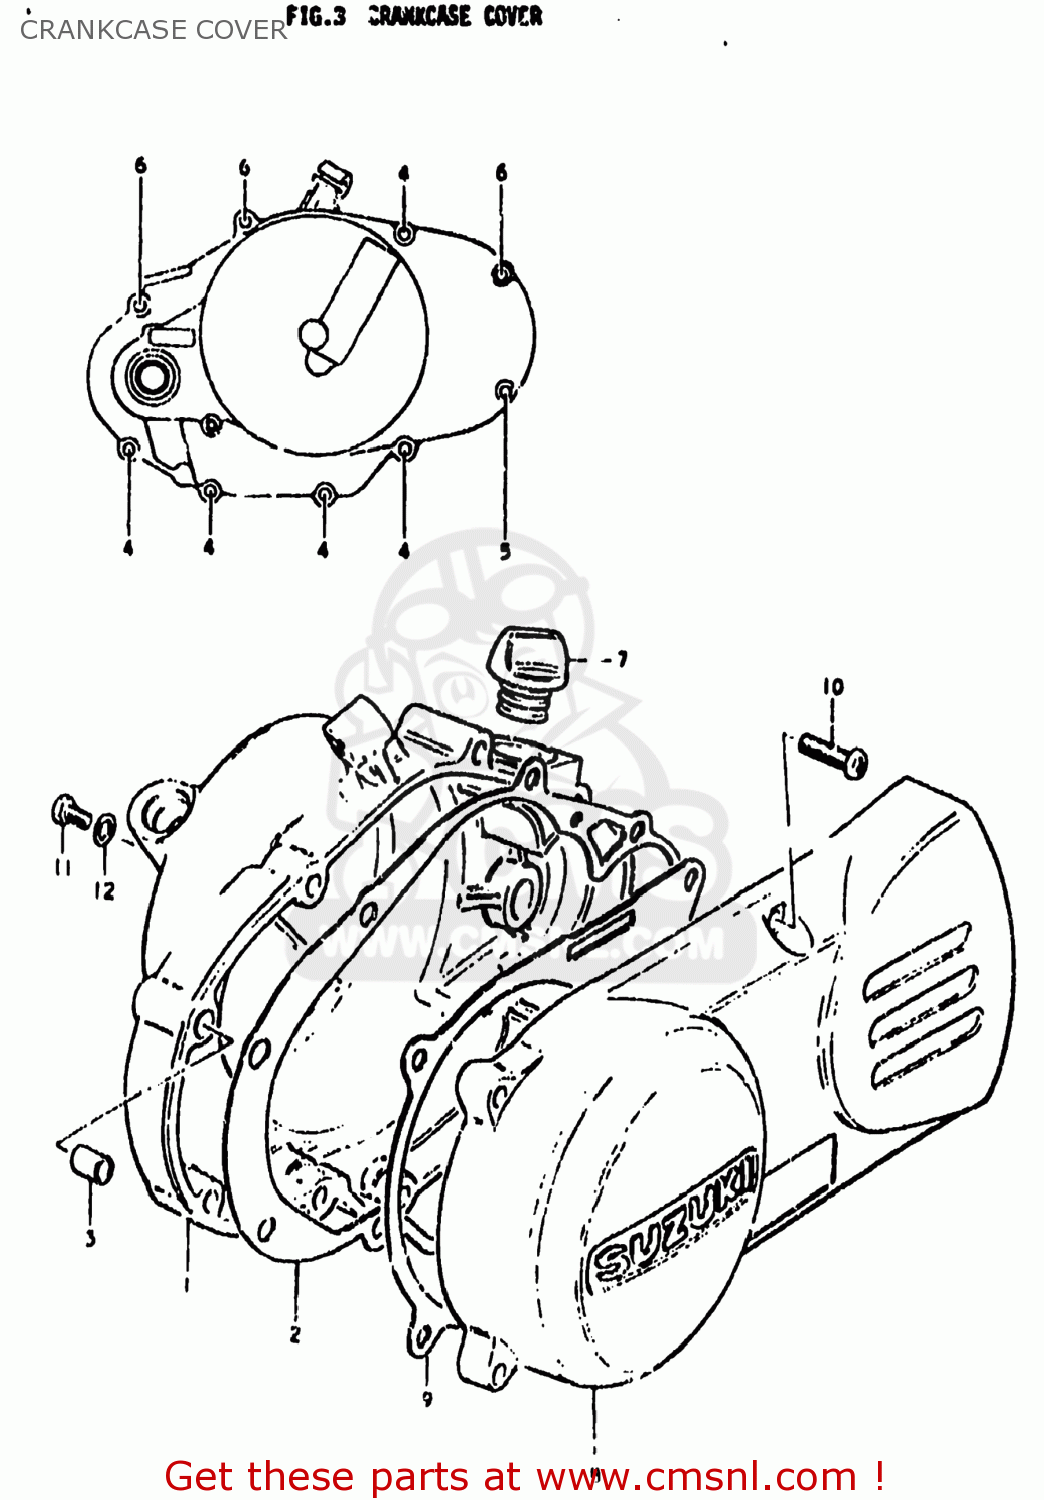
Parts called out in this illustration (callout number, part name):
1	COVER,CLUTCH
2	GASKET,CLUTCH COVER (MCA)
3	PIN
4	SCREW
5	SCREW
6	SCREW
7	PLUG
8	COVER
9	GASKET,MAGNETO COVER (NAS)
10	SCREW
11	SCREW(6X10)
12	GASKET(6.2X11X1) (NAS)
